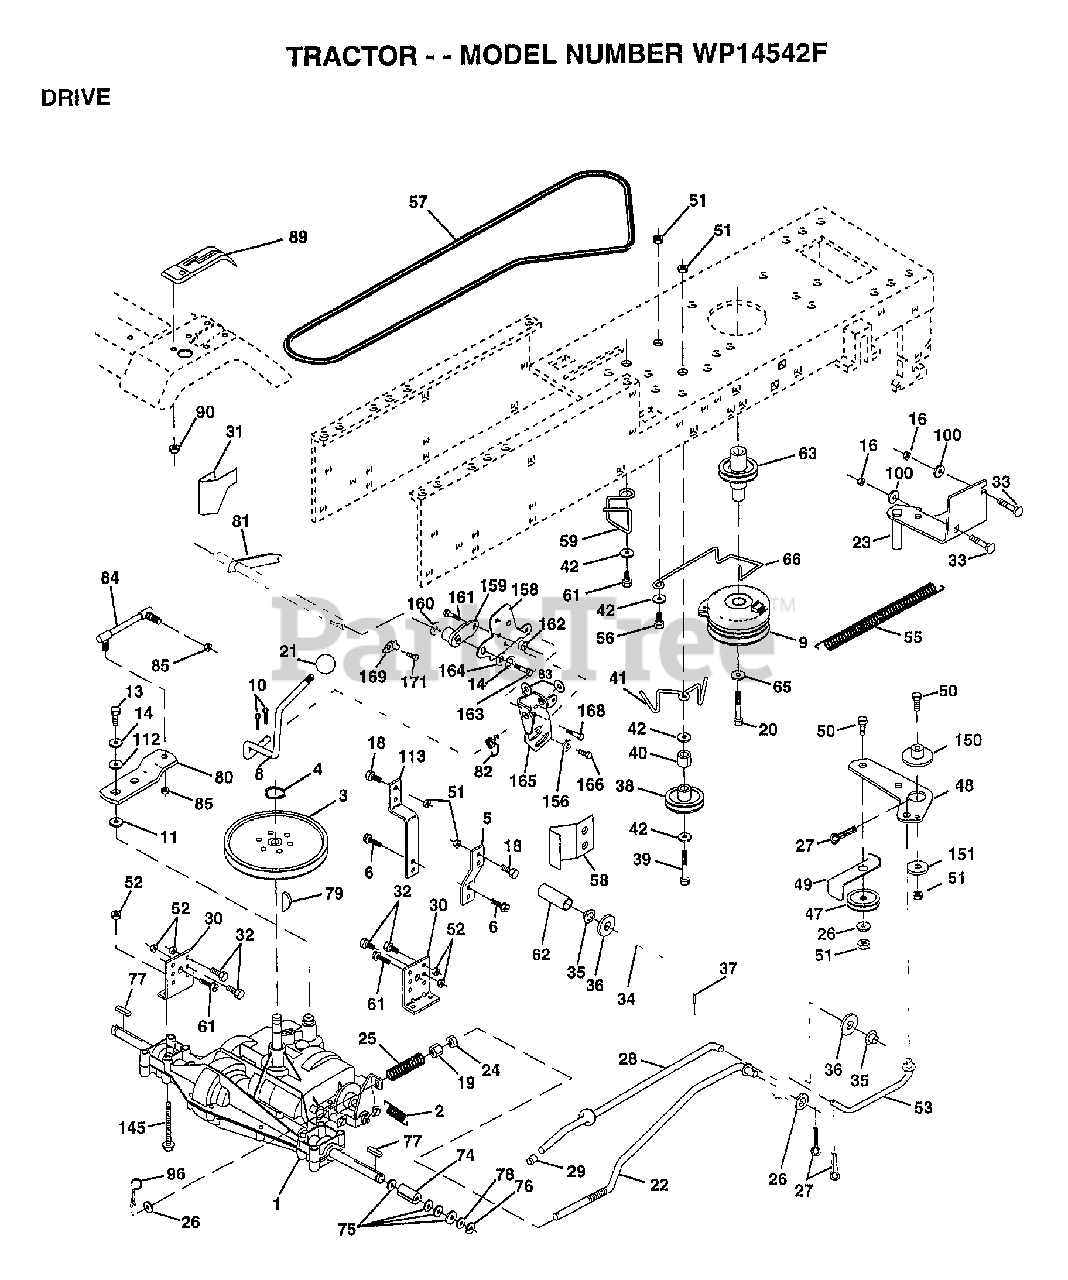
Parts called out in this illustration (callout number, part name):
2	SPRING.BRAKE.RETU
3	PULLEY TRANS
5	STRAP TORQUE
6	SCREW
8	ROD.SHIFT.FENDER.ADJ.LT.CRD
9	CLUTCH.ELECT.EVX.
10	PIN COTTER 1/8
11	WASH-SHFT PLT LT
13	BOLT.1/4-28.W/PAT
14	LOCKWASHER
16	NUT
18	BOLT
19	NUT
20	BOLT.7/16-20X4.25
21	KNOB T (1/2-HOLE)
22	BRAKE ROD
23	BRACKET.CLUT.MTG.
24	NUT
25	SPRING ROD LT
26	WASHER
27	COTTER PIN
28	ROD.BRAKE.PARK.LT
29	PLUNGER CAP T
30	TRANSAXLE MTG BKT
31	"KEEPER,BELT LH T"
32	BOLT
33	BOLT
34	SHAFT ASM-PEDAL F
35	NYLON BEARING
36	WASHER LT
38	FLAT IDLER PULLEY
39	BOLT
40	SPACER T
41	"KEEPER,BELT.IDLER FLAT"
42	WASHER
48	BELLCRANK.CLUTCH
49	RETAIN BELT
53	"LINK, CLUTCH T"
55	"SPRING, RETURN LT"
58	"KEEPER,BELT RH T"
59	KEEPER BELT CNTSP
61	SCREW
62	PEDAL COVER T
63	PULLEY.CLUTCH.EVX
65	LOCKWASHER
66	KEEPER-BELT
74	SPACER AXLE
75	WASHER
76	E-RING LT
77	SQUARE KEY
78	WASHER
80	"ARM.SHIFT.20""TIRE"
81	SHAFT.ASM.CROSS
82	"SPRING,TORSION"
83	WASHER
84	LINK.TRANSAXLE.PMST/DANA
85	NUT.CNT.LOCK.1/4
89	CONSOLE.SHIFT.SLT
90	NUT
96	RETAINER M
100	WASHER M
112	WASHER LT
113	"STRAP,TORQUE"
145	BOLT.HEX.FLGHD
150	BUSHING.BELLCRANK.GRD.DR
151	WASHER
156	WASHER.SRRTD.5/16
157	"BOLT,SHOULDER"
158	BRKT.SHIFT.MOUNT
159	HUB.SHIFT
160	WASHER
161	BOLT T
164	WASHER.5/8X.281X10GA
165	BRKT.PIVOT.LEVER
166	SCREW.5/16-18X5/8
168	BOLT.SHOULDER.5/16-18X.561
169	PLATE.FASTENING
171	SCREW LT
